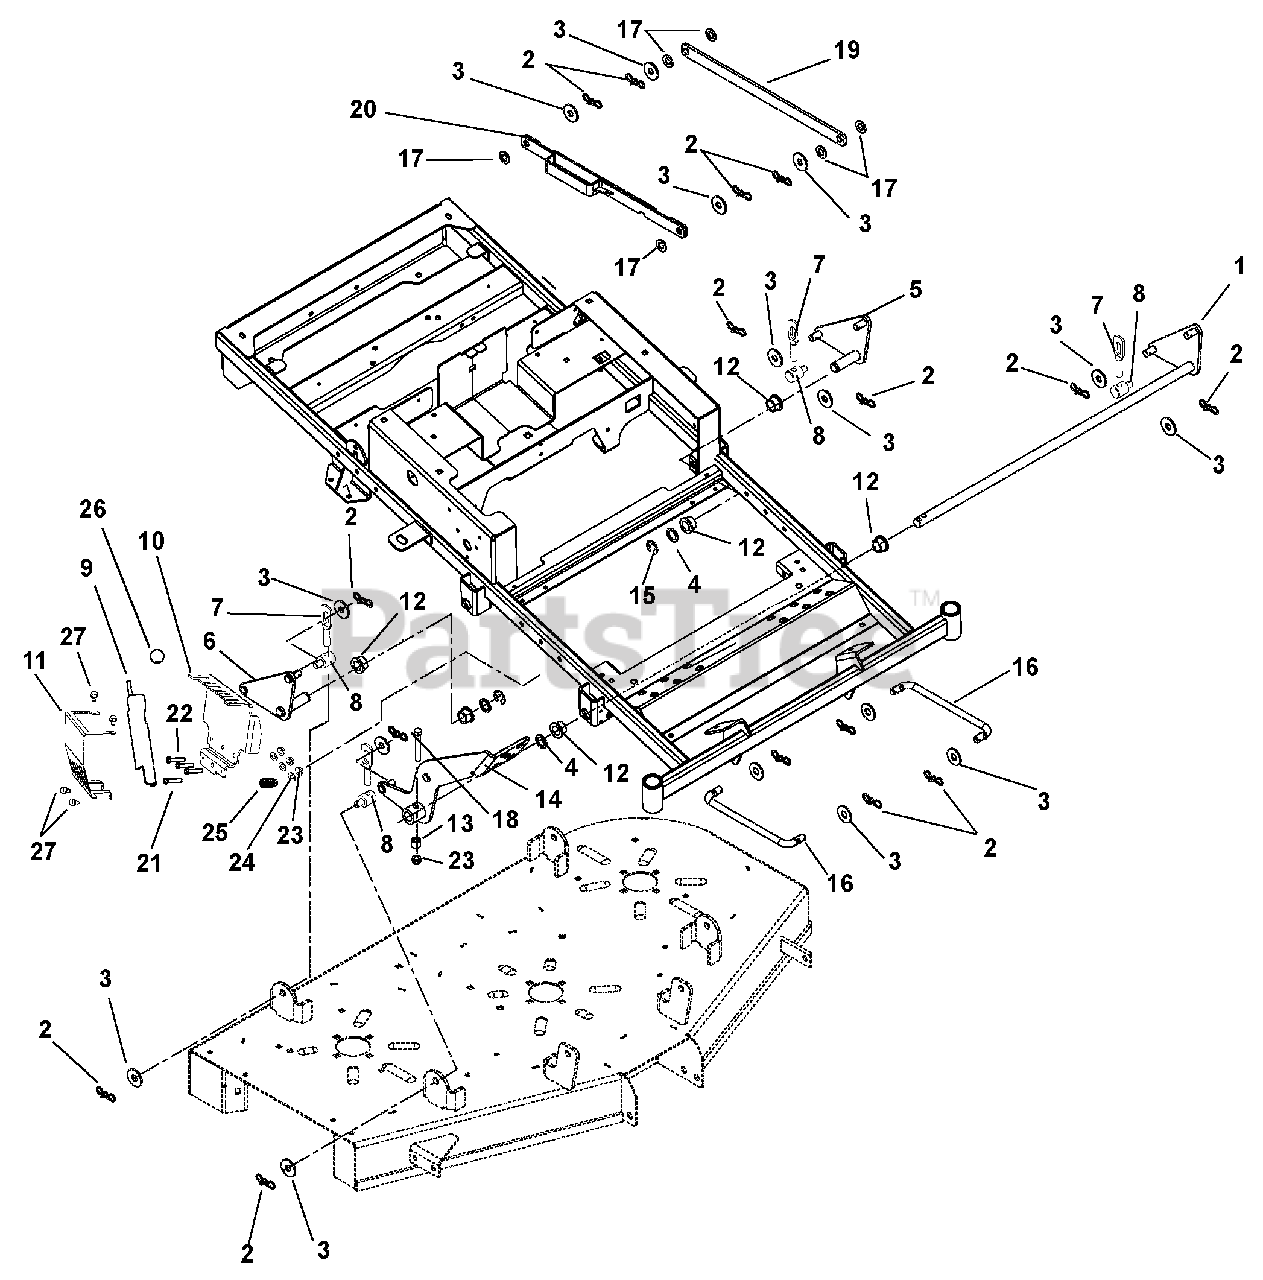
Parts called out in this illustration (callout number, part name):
1	Weldment, Deck Pivot Front
2	Pin, Bow Tie Locking Cotter .091 x 1.875
3	Washer, Flat Steel.511 x 1.441 x .125
4	Washer, Flat Steel .754 x 1.125 x .062
5	Weldment, Deck Pivot ZTXL Rear Left Hand
6	Weldment, Deck Pivot ZTXL Rear Right Hand
7	Link, Deck
8	Trunnion .50
9	Lever, Weldment HOC XL
10	Bracket, HOC XL
11	Guard, Plate Styled HOC
12	Bushing, Flange .750 x 1.000 x .625 x 1.250
13	Bushing, Sleeve .391 x .688 x .52
14	Weldment, XL Foot Pedal
15	Ring, Retaining-External .750 x .050
16	Link, Drag
17	Washer, Flat Nylon .52 x 1.00 x .08
18	Bolt, Hex .38-16 x 2.50 Grade 5
19	Link, Lift
20	HOC, Link Retaining XL
21	Bolt, Hex .38-16 x 2.25
22	Bolt, Hex .38-16 x 1.75 Grade 5
23	Nut .38-16 Nyloc Flange
24	Washer, Flat Steel .38 x .875 x .083
27	Screw, Tapping Hex Washer Head Thread Rolling .25-20 x .50 YWZ
